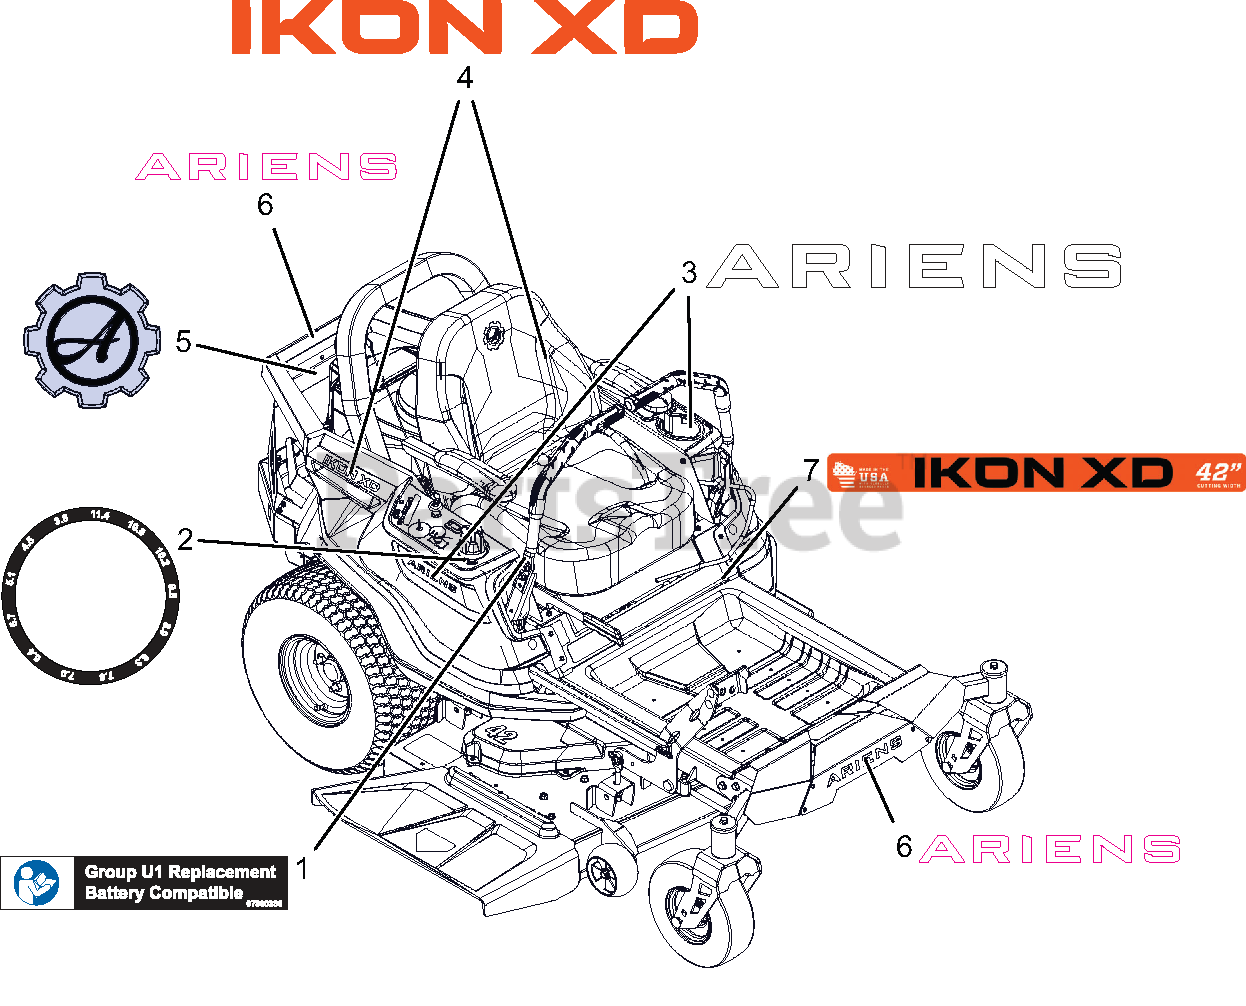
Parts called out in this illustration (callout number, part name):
1	DECAL, U1 BATTERY REPLACEMENT
2	DECAL, CUT HEIGHT - IKON CE
3	DECAL, ARIENS (6.50")
4	DECAL, FENDER - IKON XD
5	DECAL- ARIENS GEAR BADGE
6	DECAL - ARIENS 9.625"
7	DECAL, IKON XD - 42
